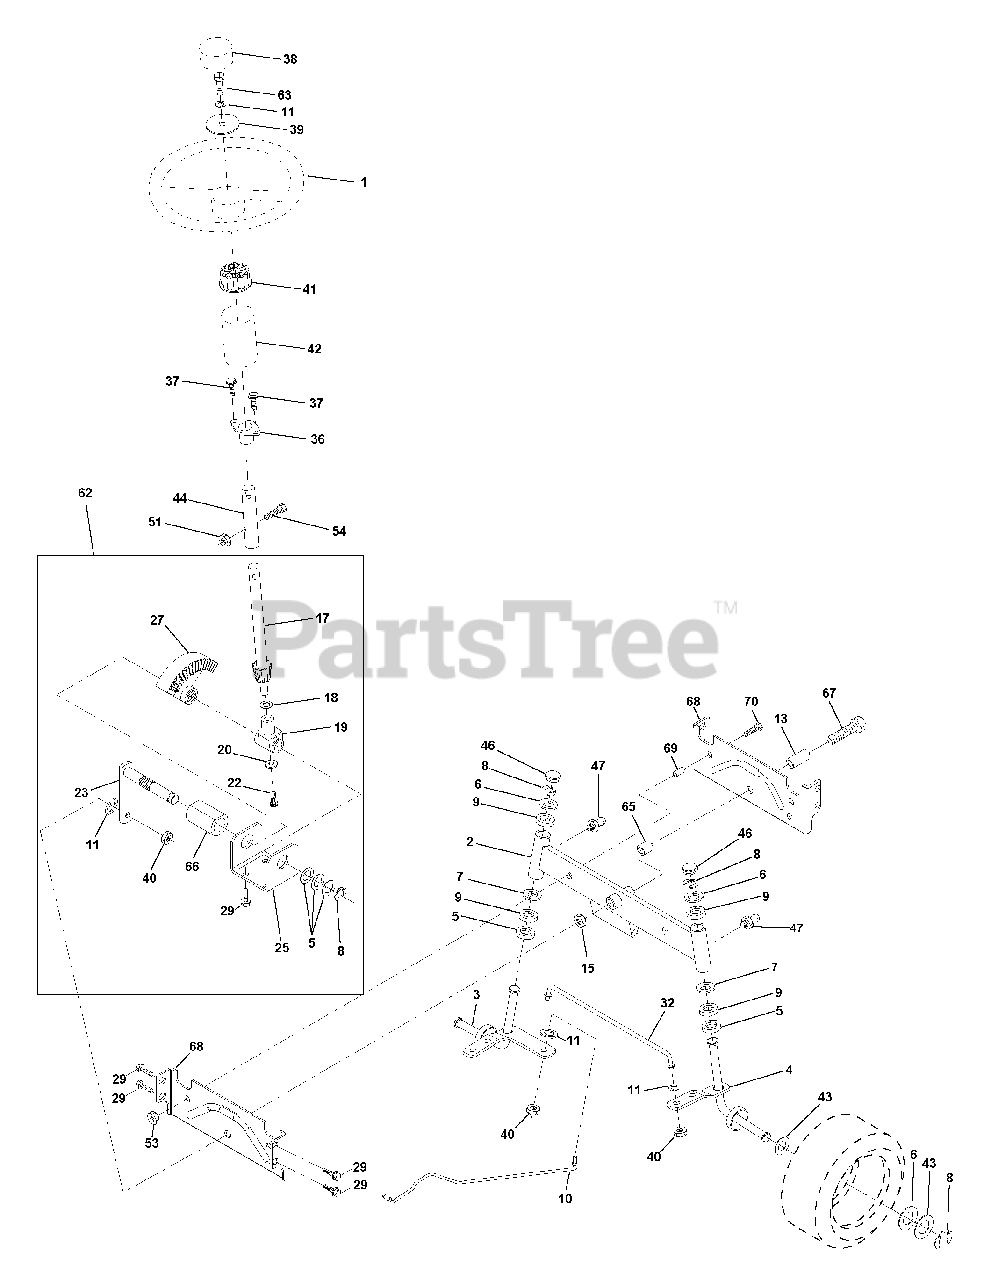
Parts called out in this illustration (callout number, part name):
1	Wheel Steering
2	Axle Front Casting Machined
3	Spindle Asm LH
4	Spindle Asm RH
5	Bearing Race Thrust Harden
6	Washer 25/32 X 1-5/8 X 16 Ga
7	Washer 27/32 X 1-1/4 X 16 Ga
8	Ring Klip #t5304-75
9	Bearing Col Strg Blk
10	Link Drag Extended Cast
11	Washer Lock Hvy Hlcl Spr 3/8
13	Bearing Axle STLT/GT
15	Nut Lock Flange 5/8-11 Unc
17	Shaft Asm Strg
18	Washer Thrust 515x 750x 033
19	Support Shaft
20	Washer Shim 1/4 X 5/8 X 062
22	Screw Hex Sckt 1/4-20 x 5/8
23	Shaft Asm Pittman
25	Bracket Steering
27	Gear Sector
29	Screw Thdrol 3/8-16x3/4 Ty-tt
32	Rod Asm Tie Ball Adj. VGT
36	Bushing Strg
38	Insert Cap Strg Wh Au
39	Washer 13/32 X 2-3/8 X 8 Ga
40	Lock nut
41	Adaptor Wheel Strg
42	Boot Steering Shaft
43	Washer 25/32 X 1 1/4 X 16 Ga
44	Extension Steering Shaft LR/LT
46	Cap Spindle Fr Top Blk
47	Fitting Grease
51	Nut Lock Hex w/Ins 5/16-18
53	Nut Crownlock 3/8-16 UNC
54	Bolt Fin Hex 5/16-18 Unc x 1-1/4
62	Kit, Steering Assembly Svc
63	Bolt Fin Hex 3/8-16unc x 1 Gr. 5
65	Spacer Axle
66	Bearing Arm Pittman
67	Bolt, Fin Hex 5/8-11 UNC x 2-3/4
68	Brace, Axle
69	Spacer Brace Axle
70	Bolt Fin Hex 3/8-16 UNC x 2-1/4
